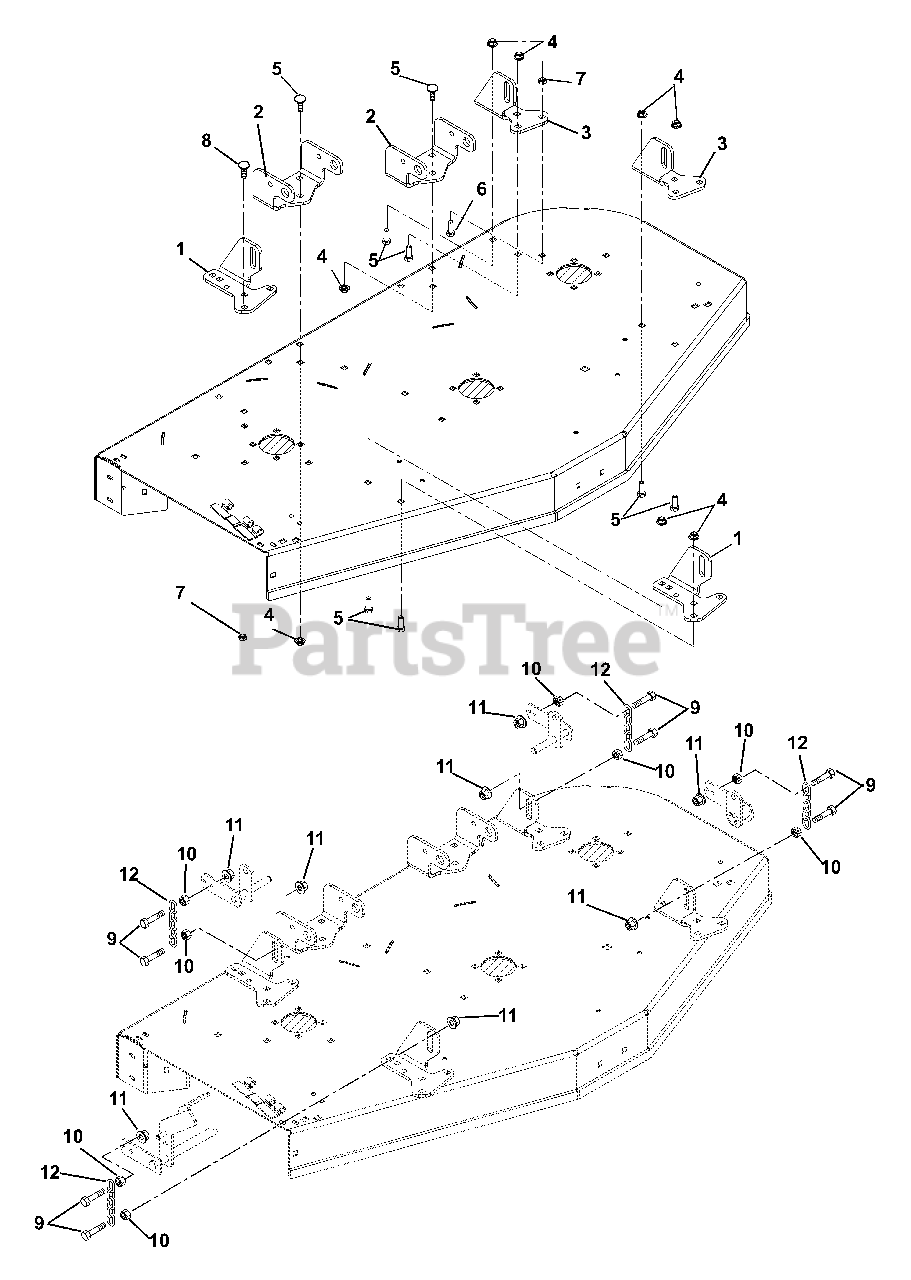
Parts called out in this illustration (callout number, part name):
1	Bracket, Deck Hanging
2	Bracket, Deck Mounting
3	Bracket, Deck Hanging
4	Nut, 3/8-16 Flange Nyloc
5	Bolt, Round Head Square Neck .38-16 x 1.00 Grade 5
6	Bolt, Round Head Square Neck .38-16 x 1.25 Grade 5
7	Nut, Locking Jam .375-16
8	Bolt, Round Head Square Neck .38-16 x .75 Grade 5
9	Bolt, Hex M12-1.75 x 55 Grade 5
10	Nut, Spinlock Flange M12-1.75
11	Nut, Locking Top Flange M12-1.75
12	Chain, Link
